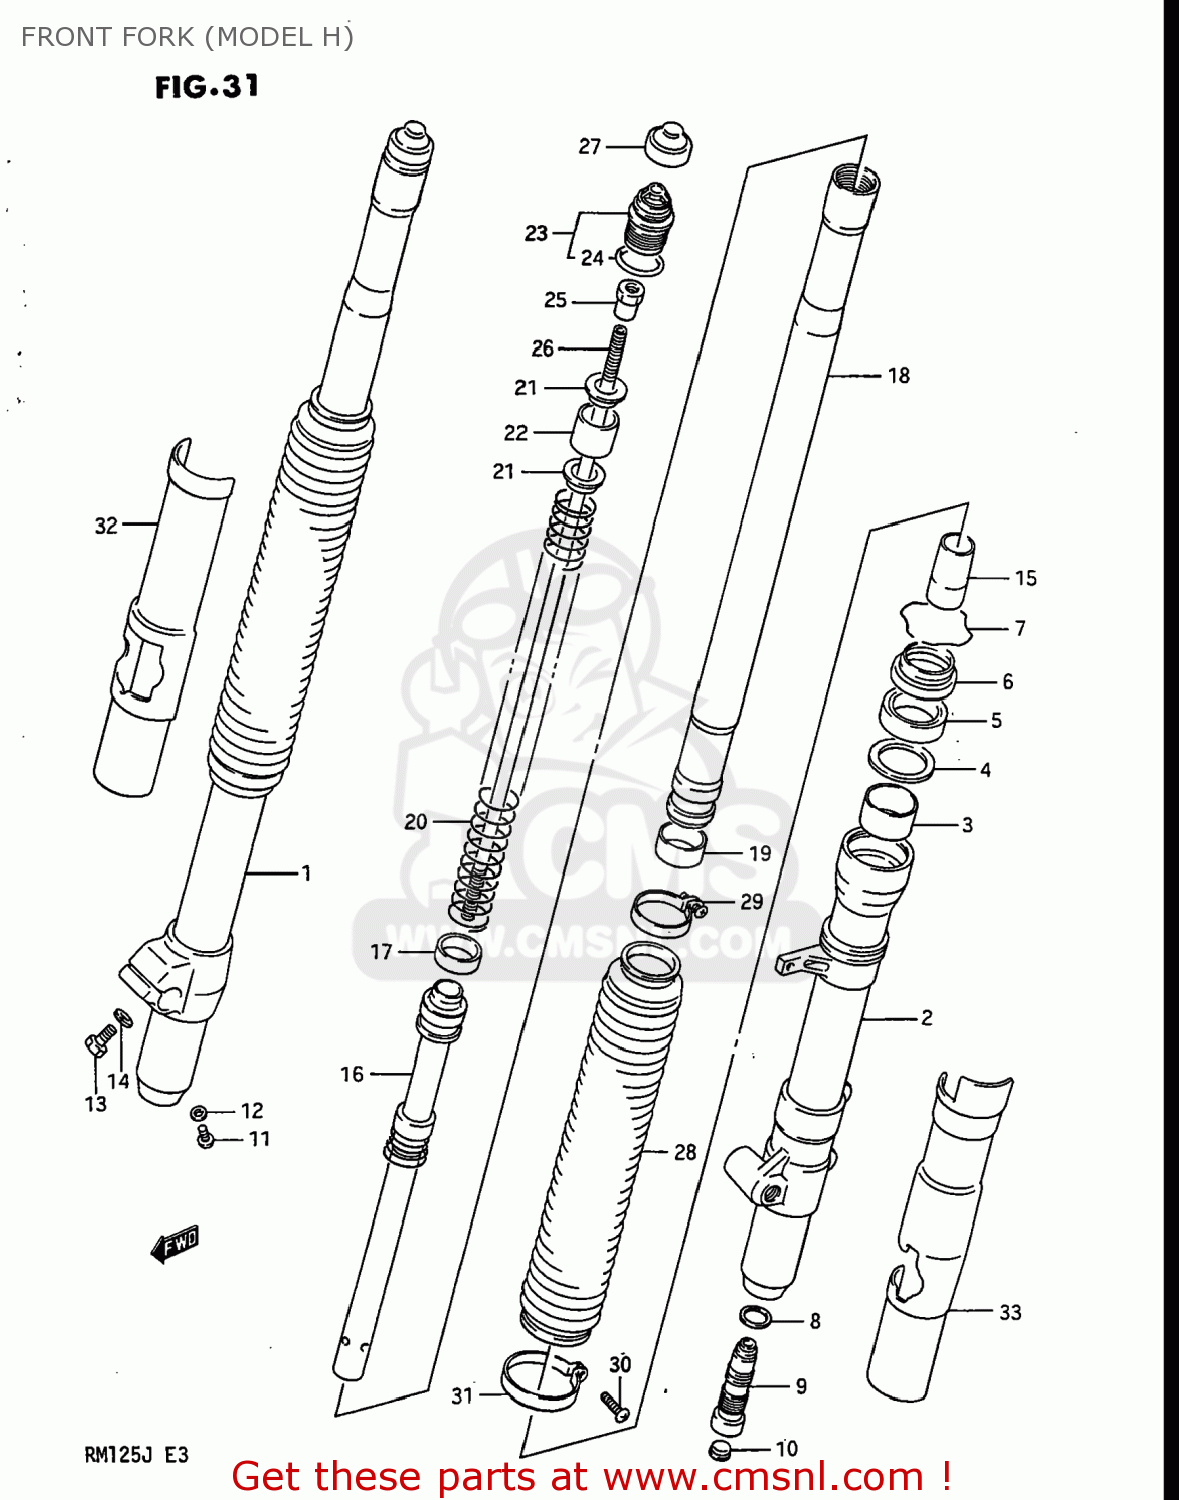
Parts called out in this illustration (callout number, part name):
1	TUBE,OUTER,RIGHT
2	TUBE,OUTER,LEFT
3	METAL,SLIDE
4	WASHER
5	OIL SEAL,FRONT FORK
6	SEAL,DUST
7	RING,STOPPER
8	GASKET
9	VALVE
10	CAP,FRONT FORK DF
11	SCREW 4X6
12	GASKET,DRAIN,PLUG (NAS)
13	BOLT
14	LOCK WASHER
15	PIECE,OIL LOCK
16	CYLINDER,FRONT FORK
17	RING,FRONT FORK PISTON
18	TUBE,INNER
19	PISTON
20	SPRING,FRONT FORK
21	GUIDE,SPRING
22	SPACER
23	CAP
24	O RING
25	NUT
26	ROD,PISTON
27	CAP
28	BOOT
29	BAND,BOOT UPR
30	SCREW,BAND BOOT(3.5X10)
31	BAND,BOOT LWR
32	PROTECTOR,RIGHT
33	PROTECTOR,LEFT
